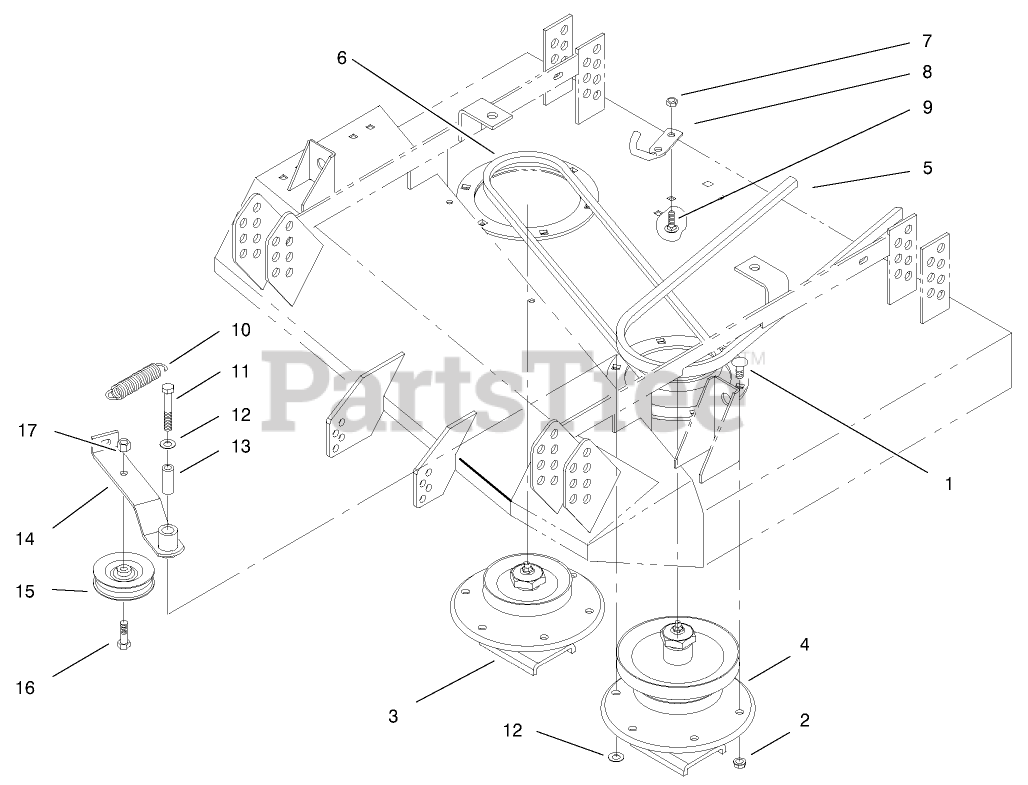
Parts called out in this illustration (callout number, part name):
1	SCREW-CARR
2	NUT-HF
3	SPINDLE ASM
4	HOUSING - SPINDLE ASM
5	V-BELT
6	V-BELT-DRIVE, DECK
7	NUT-LOCK, NI
8	ROD - SPRING
9	SCREW-CARR
10	Spring-Extension
11	SCREW-HH
12	WASHER-FLAT
13	SLEEVE-PIVOT, IDLER
14	IDLER ARM ASM
15	PULLEY-IDLER
16	SCREW-HH
17	NUT-HEX
